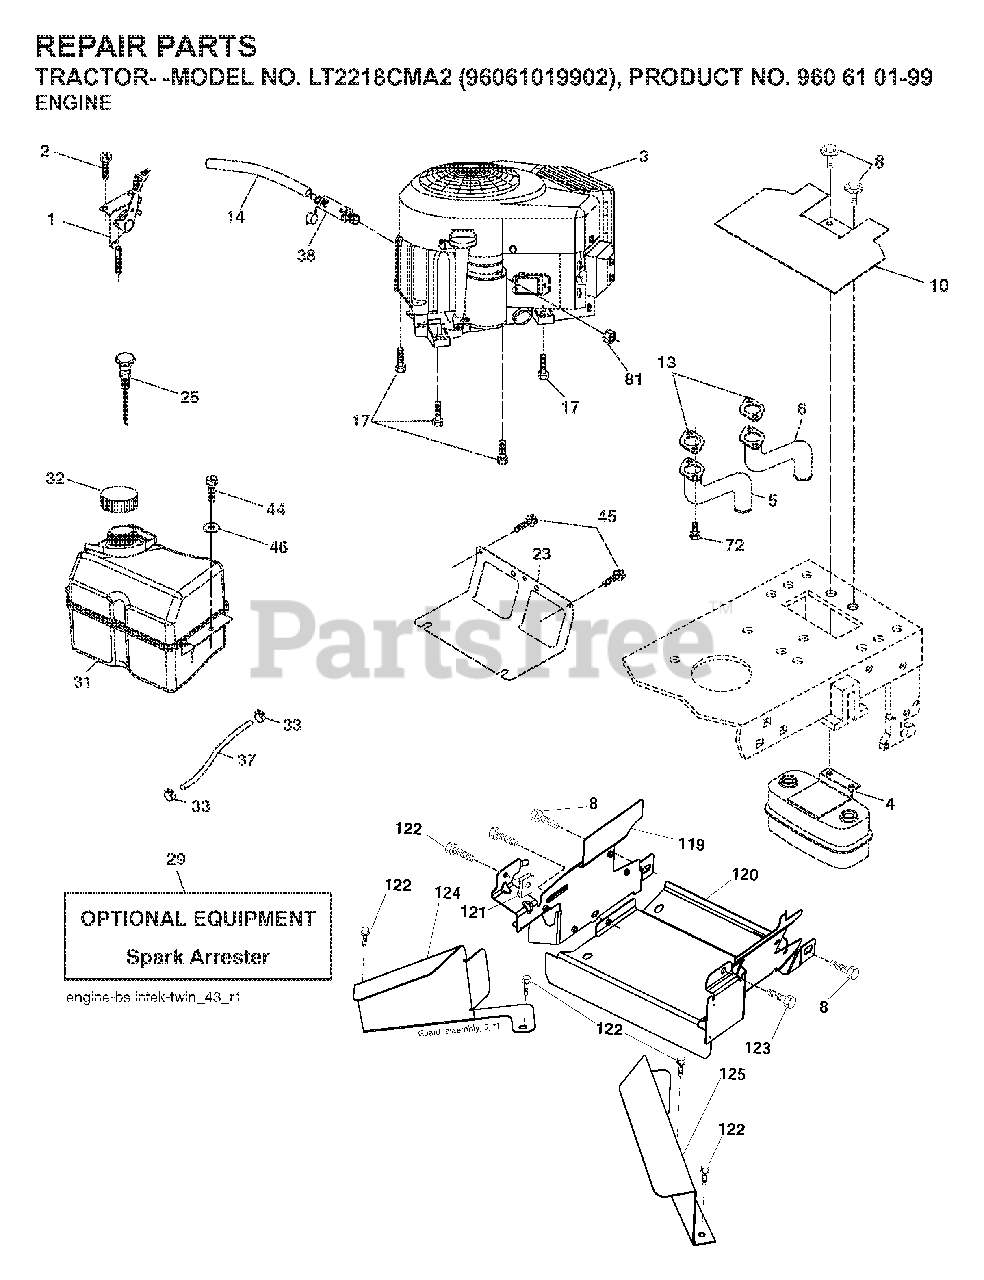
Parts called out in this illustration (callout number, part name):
1	THROTTLE CABLE
2	SCREW
4	MUFFLER.TWIN.CYL.LOW.TONE
5	EXHAUST TUBE RH
6	TUBE MANIFOLD LH
8	BOLT, 5/16-18 X 1 3/4
10	RP SHIELD HEAT MUFFLER
13	GASKET.MUFFLER
14	TUBE, DRAIN OIL ASM.
17	SCREW.3/8-16
23	SHEILD.BROWNING.DBR.GUARD
25	CONTROL CHOKE
29	ARRESTER SPARK (OPTIONAL)
31	TANK FUEL
32	FUEL CAP
33	HOSE CLAMP
37	LINE.FUEL.20
38	PLUG DRAIN OIL EASY
44	SCREW HEXWSHR 1/4-20X3/4
45	SCREW, 3/8-16X3/4
72	SCREW.SOCKET.HEAD.5/16-18
81	NUT
122	SCREW.1/4-20X5/8
123	SCREW, 5/16-18 X 1/2
